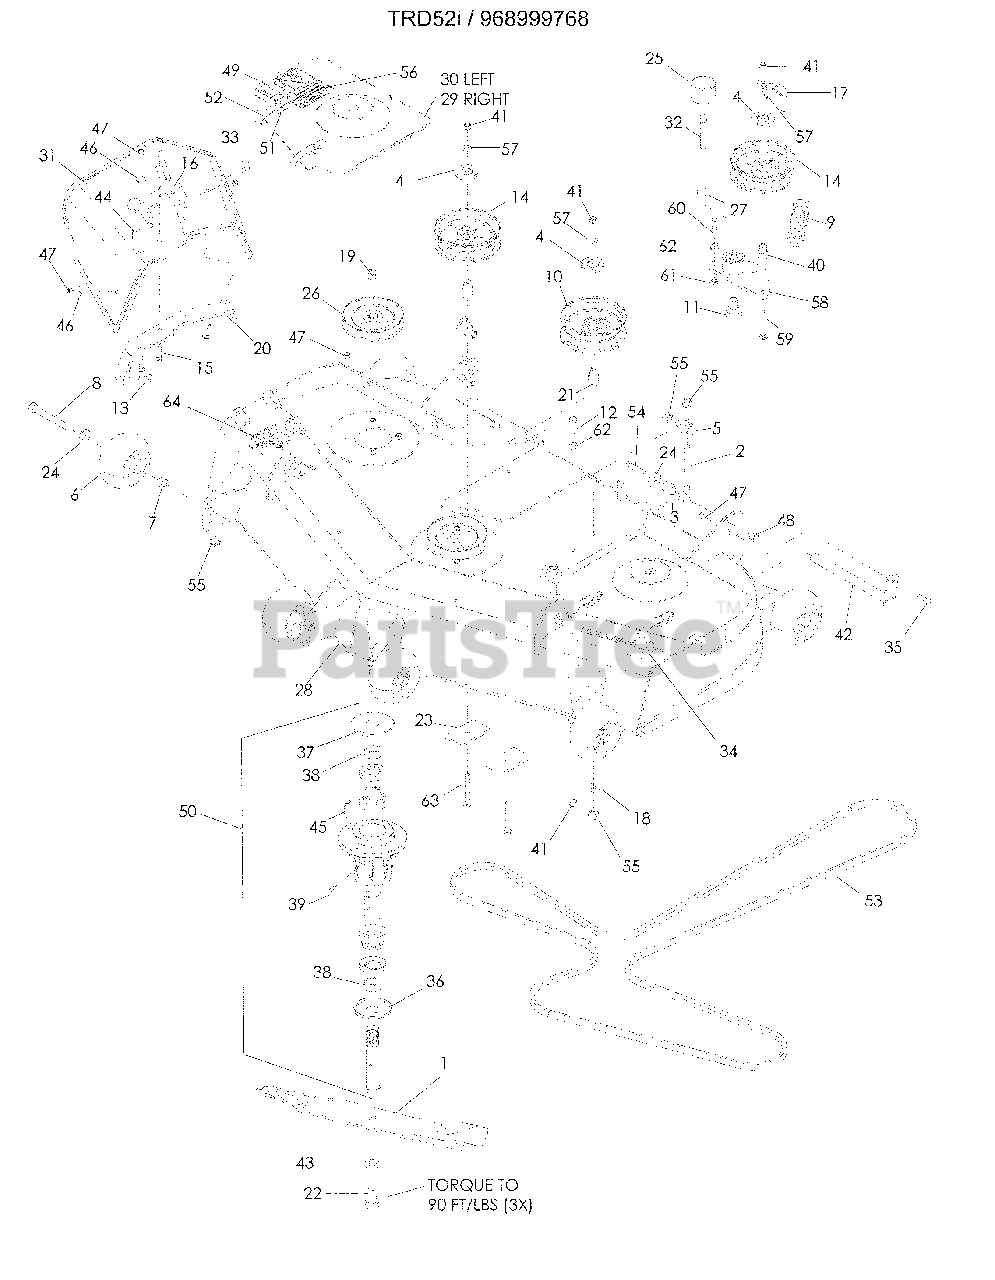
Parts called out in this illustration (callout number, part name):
1	BLADE, 18"
4	SHIELD, DUST
6	ROLLER, ANTI SCALP
7	NUT ½- 13
8	HCS ½-13 x 4
10	PULLEY, IDLER
11	PIVOT, BEARING
12	HCS 3/8- 16 x 1¼
13	RHSNB 5/16-18 x 1¼
14	PULLEY, IDLER
15	RHSNB 5/16-18 x 1½
16	BRACKET, RUBBER CHUTE
17	GUIDE, BELT
18	SUPPORT, WASHER
19	NUT ¾-16 FLANGE
20	REINFORCEMENT, BRCKET
21	BUSHING, IDLER
22	HCS 5/8-18 x 1¼
23	PAD
25	CAP, VINYL
27	WASHER ½ BELLEVILLE
28	DECK w/ DECALS
29	BELT SHIELD, RIGHT
30	BELT SHIELD, LEFT
31	DISCHARGE CHUTE
32	HCS ½-13 x 3¼
33	PIN, CHUTE PIVOT
34	DECAL, TUNNEL RAM
35	HCS 5/16-18 x 1
36	DUST CAP, BOTTOM
37	DUST CAP, TOP
38	SHAFT SEAL
39	GREASE POPPET
40	BUSHING, IDLER
41	NUT 3/8-16 NYLOC
43	LOCKWASHER 5/8
44	PIN COTTER, 1/8 x ¾
45	HCS 5/16-18 x 1¼
46	WASHER 5/16
47	NUT 5/16-18 NYLOC
48	NUT 7/16-14 CNTRLK, GR A
49	DECAL, SEVERING
50	SPINDLE ASSEMBLY
52	DRAW LATCH
54	HCS 7/16-14 x 1¾
55	NUT ½-13 NYLOC
56	DECAL, WARNING
57	WASHER 3/8 THICK
58	ARM w/ BEARINGS, IDLER
59	RHSNB 3/8-16 x 2¾
60	HCS 3/8-16 x 1½ GR8
61	NUT 3/8-16 JAM
62	NUT 3/8-16 WHIZLK
63	HCS 3/8-16 x 3
64	DECAL, CPSC
